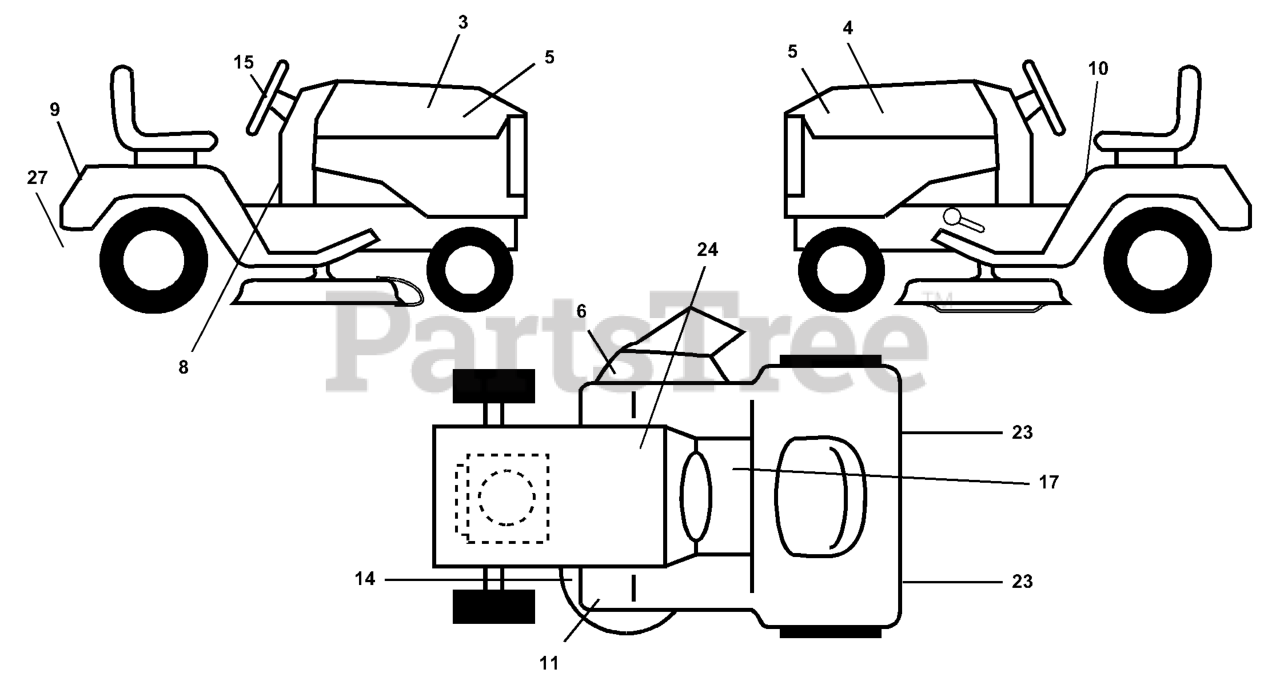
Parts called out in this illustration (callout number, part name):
3	DECAL, HOOD RH
4	DECAL HOOD(L)GTH2550XP
5	DECAL HOOD
6	DECAL.WARN.KEEP.HAND.AWAY
8	DECAL, DASH
9	DECAL, FENDER
10	DECAL FENDER DANGER
11	DECAL, CLUTCH/BRAKE
14	DECAL V-BELT SCHEMATIC
15	DECAL.WHEEL.STEERING.HUSQ.PERM
17	DECAL PARK BRAKE
23	REFLECTOR-TAIL YT
24	DECAL BTRY SYMBOLS
27	DECAL.BYPASS.FENDER.CRD.LT.YT
